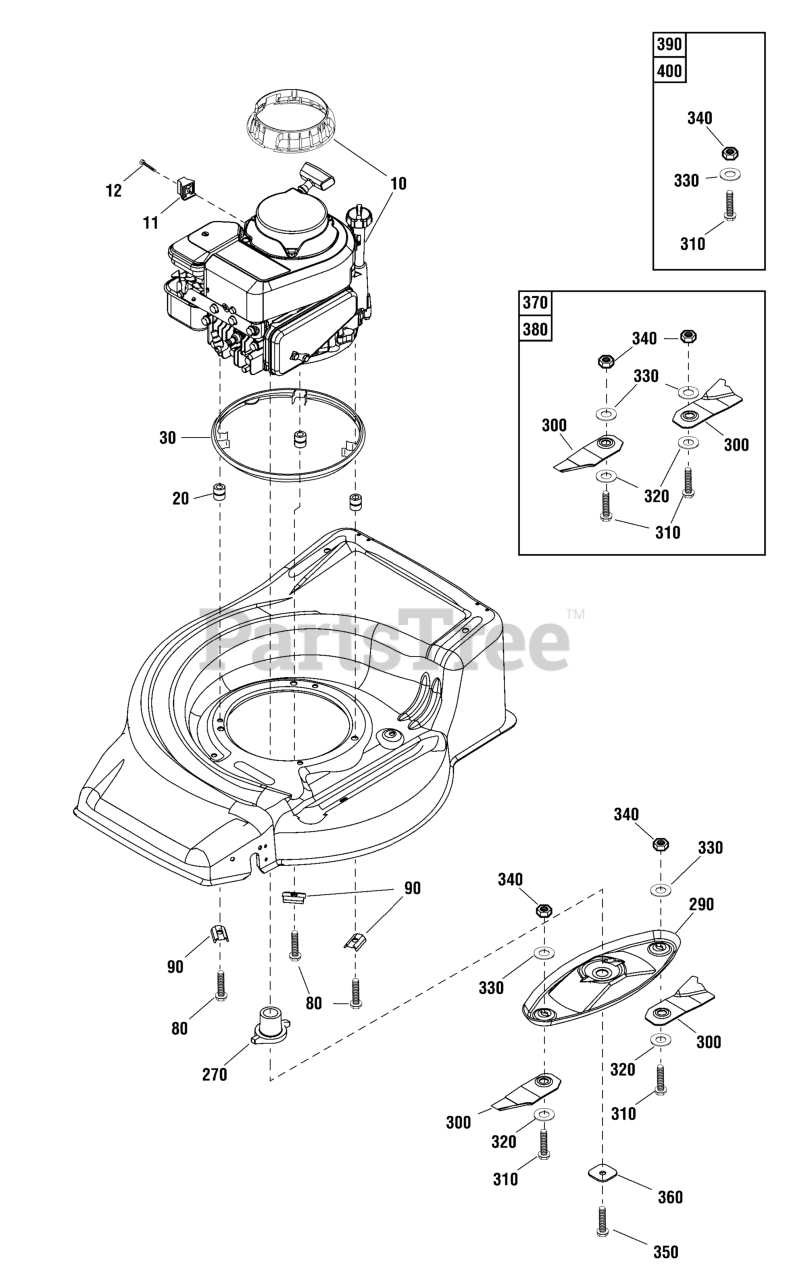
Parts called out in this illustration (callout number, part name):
10	* ENGINE, Briggs & Stratton Series 450
11	SPACER, Throttle Mount
20	SPACER, 20mm
30	SPACER RING
80	BOLT, Taptite, 3/8 UNC x 50
90	SADDLE PLATE
270	SLEEVE, Locking, 4 Stroke
290	BLADE Disc, Oval
300	BLADE, Low Profile
310	BOLT, Blade
320	WASHER, Blade Tension
330	WASHER, Belleville
340	NUT, Nylock, 3/8 UNC
350	BOLT, Blade Disc
360	WASHER, Blade Disc
370	KIT, Blade & Bolt (1 Pair)
380	KIT, Blade & Bolt, Bulk Pack (50 Pairs)
390	KIT, Hardware, Blade Mounting, (1 Pair)
400	KIT, Hardware, Blade Mounting , Bulk Pack (50 Pair)
